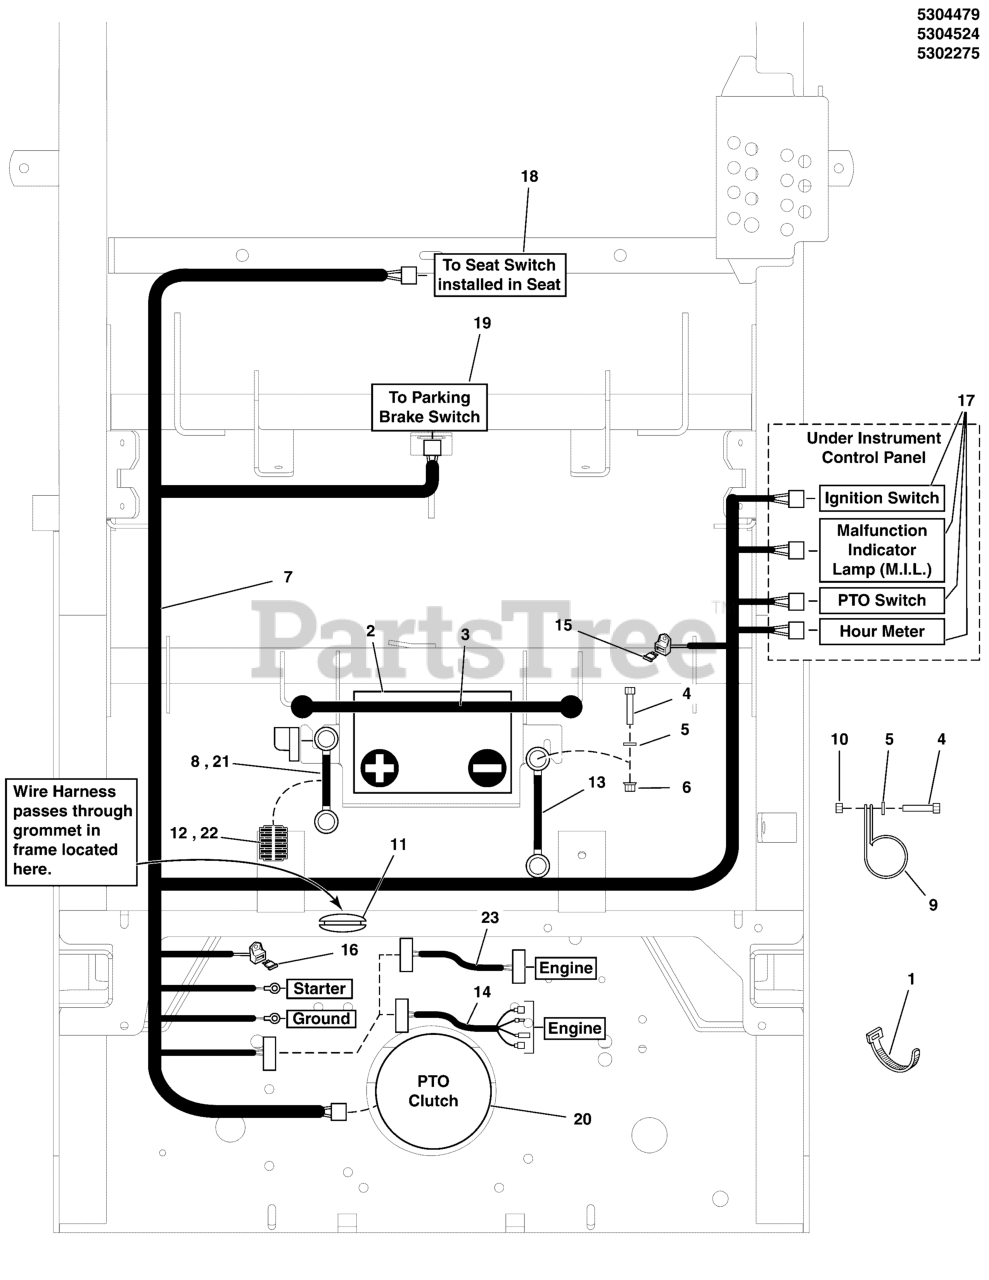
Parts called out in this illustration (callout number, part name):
1	TIE, SELF-LOCKING, 12"
2	BATTERY, WET ( BCIU1, 350 CCA)
3	STRAP, BATTERY, 14 LONG, Rubber
4	BOLT, 1/4"-20 X 3/4" GD5 YZ
5	WASHER, 1/4 SAE
6	NUT, 1/4-20 HEX SERR. FLANGE
7	WIRE HARNESS, MAIN, LG, ZTR
8	BATTERY CABLE, POS, 22, 1/4-5/16
9	CLAMP, VINYL INSULATED, 1.00
10	NUT, 1/4-20 Hex Nylock Flange
11	GROMMET, 2" ID
12	WIRE LOOM, 3/8 ID X 17 IN
13	BATTERY CABLE, NEG, 22, 1/4-5/16
14	WIRE HARNESS, JUMPER, KAWI - LARGE HARNE
15	FUSE, ATO, 25 AMP
16	FUSE, ATO-15 (15 AMP)(SV)
17	Refer to: Instrument Control Panel Group
18	Refer to: Seat Mount & Floor Group
19	Refer to: Parking Brake Group
20	Refer to: Engine & PTO Group
21	BATTERY CABLE, POS, 30, 1/4-5/16
22	WIRE LOOM, 3/8 ID X 17 IN
23	WIRE HARNESS, VANGUARD BIG BLOCK,JUMPER
